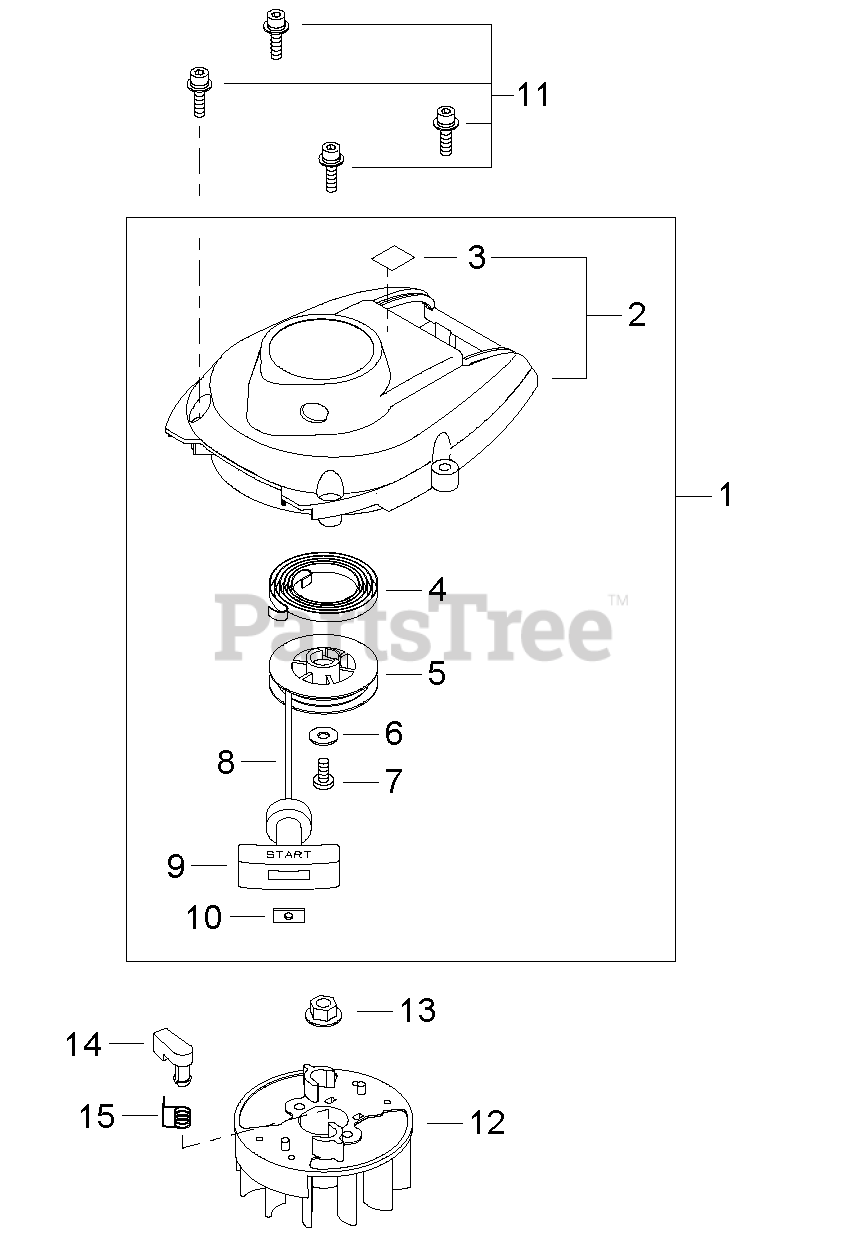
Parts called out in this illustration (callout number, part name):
1	STARTER ASSY, RECOIL
2	CASE ASSY, RECOIL STARTER
3	LABEL, CAUTION - HOT
4	SPRING, RECOIL
5	REEL, ROPE
6	WASHER 5
7	SCREW 5
8	ROPE, STARTER
9	GRIP, STARTER
10	RETAINER, ROPE
11	BOLT, ADHESIVE M5×20
12	FLYWHEEL
15	SPRING, TORSION
